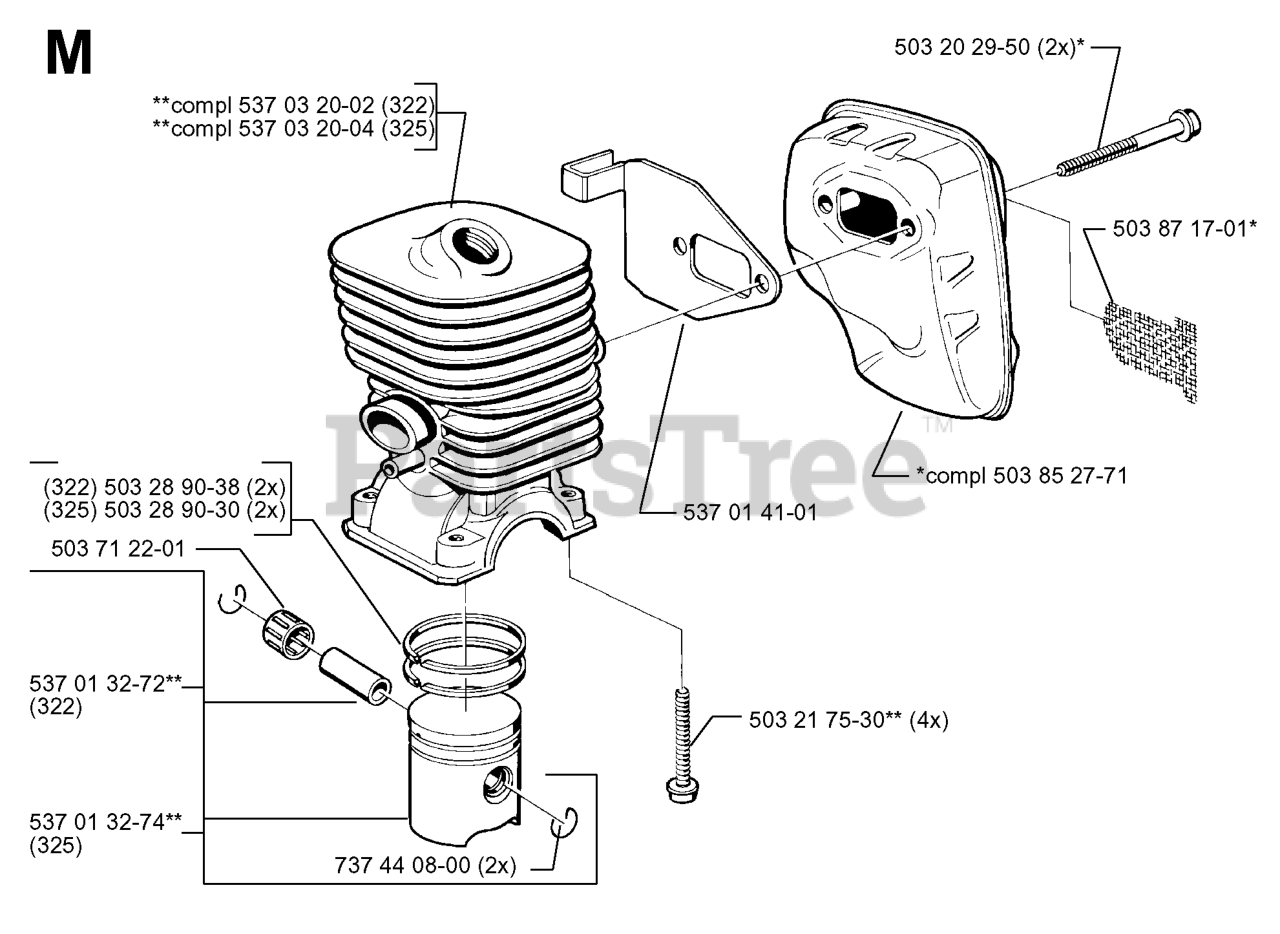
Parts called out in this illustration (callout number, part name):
1	DECAL.INTERNATIONL.CUTFINGER
2	DECAL
3	DECAL, DEFLECT WARNING
4	DECAL PARK BRAKE
5	LABEL
6	Decal, Fender 100 DB/CE
7	DECAL
8	DECAL V BELT SCHEMATIC
9	DECAL BTRY SYMBOLS
12	DECAL
16	DECAL.BADGE.170MM.TEXTLOGO.
